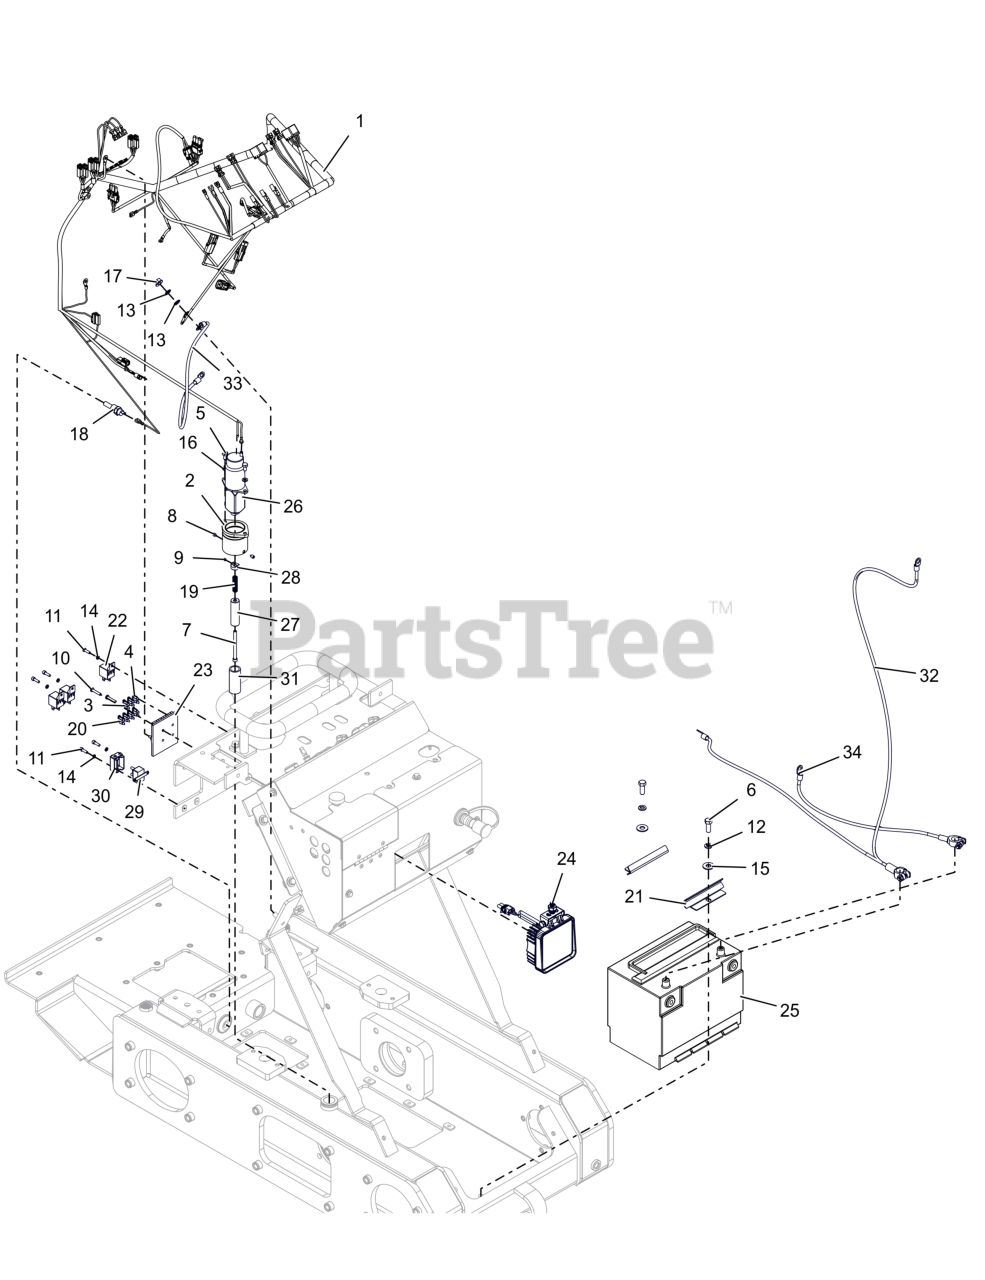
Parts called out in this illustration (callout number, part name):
1	HARNESS, ELECTRICAL
2	MOUNT, BRAKE SOLENOID (BLACK)
3	FUSE, 30 AMP.
4	FUSE, 15 AMP.
5	BLT,HEX .25-20X.50 G5 ZCC
6	BLT,HEX .38-16X1.00 G5 ZCC
7	SCR, SKH .25-28X3.00
8	SCR-SET, 25-20X.375 SKHFDP
9	SCR-SET, 10-24 X .375 SKHCONP
10	SCR, MCH-10-32X1.00 ZCC PHD
11	SCR, SKH 10-32X.625 GR5 ZCC
12	WSHR,LK-REG .375X.094 ZCC
13	WSHR-LK-INT .375 ZCC
14	@WSHR-LK #10X.047 REG YWZC
15	WSHR,FLT .438X1.00X.083 ZCC
16	WSHR,LK-REG .250X.062 ZCC
17	NUT-LK-CTR-FLG .375-16 GF ZCC
18	SWITCH, TEMPERATURE
19	SPRG, COMPRESSION
20	FUSE-10 AMP ATC TYPE
21	HOLDDOWN, BATTERY (BLACK)
22	RELAY, W/BRACKET-12V 40A SPDT
23	MODULE, 8-WAY PDM
24	LIGHT, 4.3 X 5.0 LED
25	BATTERY, GROUP 34HC 685CCA
26	SOLENOID, BRAKE
27	BAR, BRAKE PIN
28	LOCK, BRAKE
29	BREAKER, CIRCUIT
30	BOOT, CIRCUIT BREAKER
31	BUSHING, SLEEVE .75X1.00X2.38
32	CABLE- POS 35.00 - 49.00
33	CABLE- NEG 18.25 IN
34	CABLE- NEG 32.75 IN
